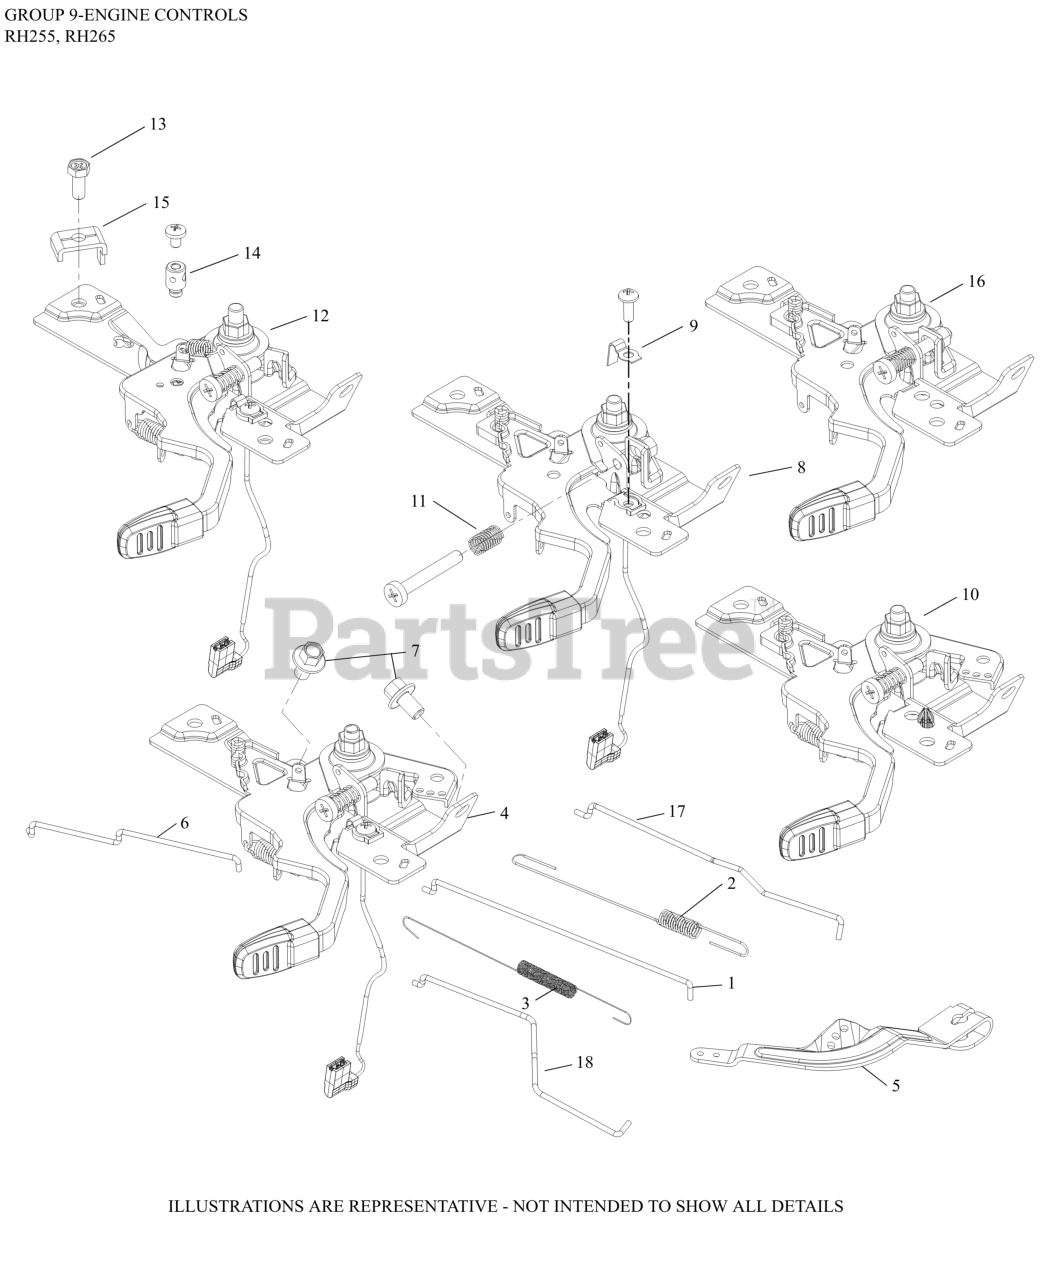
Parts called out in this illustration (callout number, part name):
1	LINKAGE, GOVERNOR-USE 18 079 05-S
2	SPRING, GOVERNOR
3	SPRING, LINKAGE
5	LEVER, GOVERNOR
7	SCREW, FLG M6X1.0X10
8	FIXED SPEED CONTROL ASSEMBLY
9	PLATE, KILL SWITCH
11	SPRING, COMPRESSION
